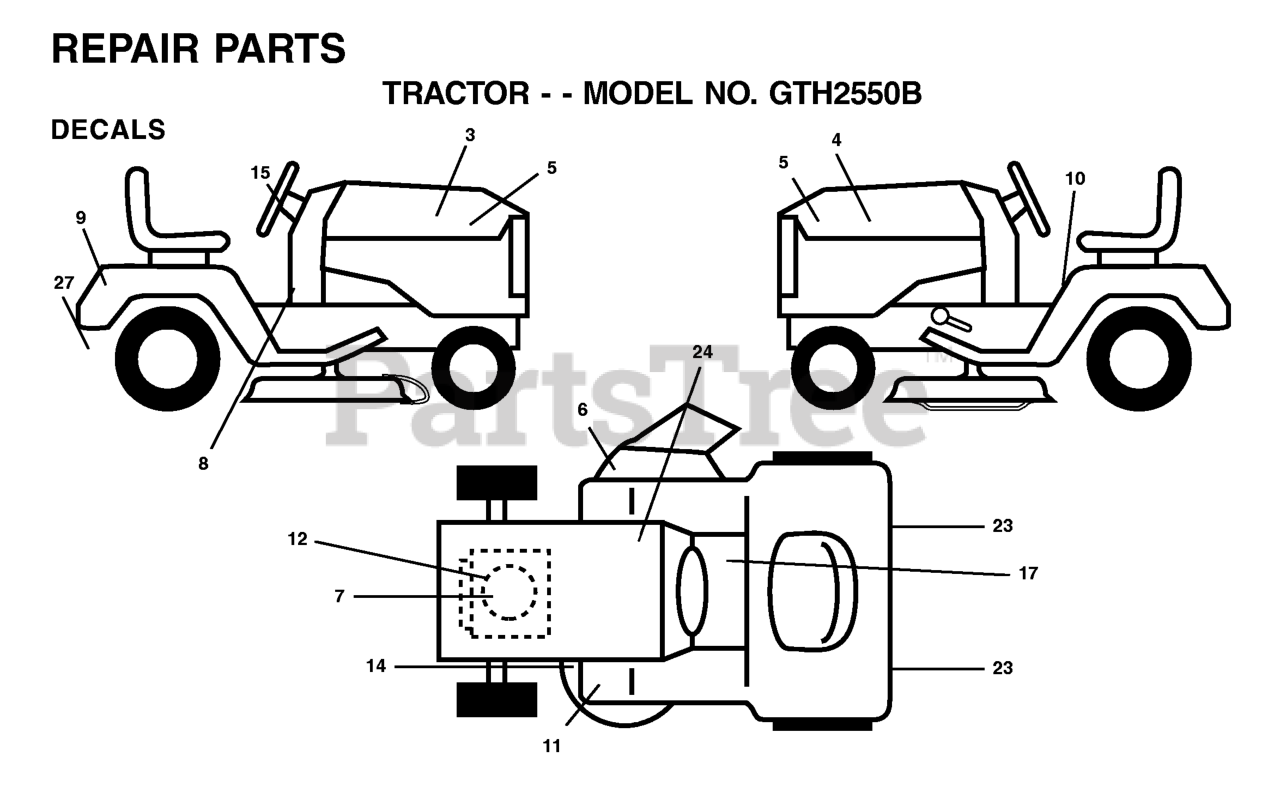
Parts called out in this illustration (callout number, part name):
6	DECAL.WARN.KEEP.HAND.AWAY
8	DECAL, DASH
9	DECAL, FENDER
10	DECAL FENDER DANGER
14	DECAL V-BELT SCHEMATIC
15	DECAL.WHEEL.STEERING.HUSQ.PERM
17	DECAL PARK BRAKE
23	REFLECTOR-TAIL YT
24	DECAL BTRY SYMBOLS
